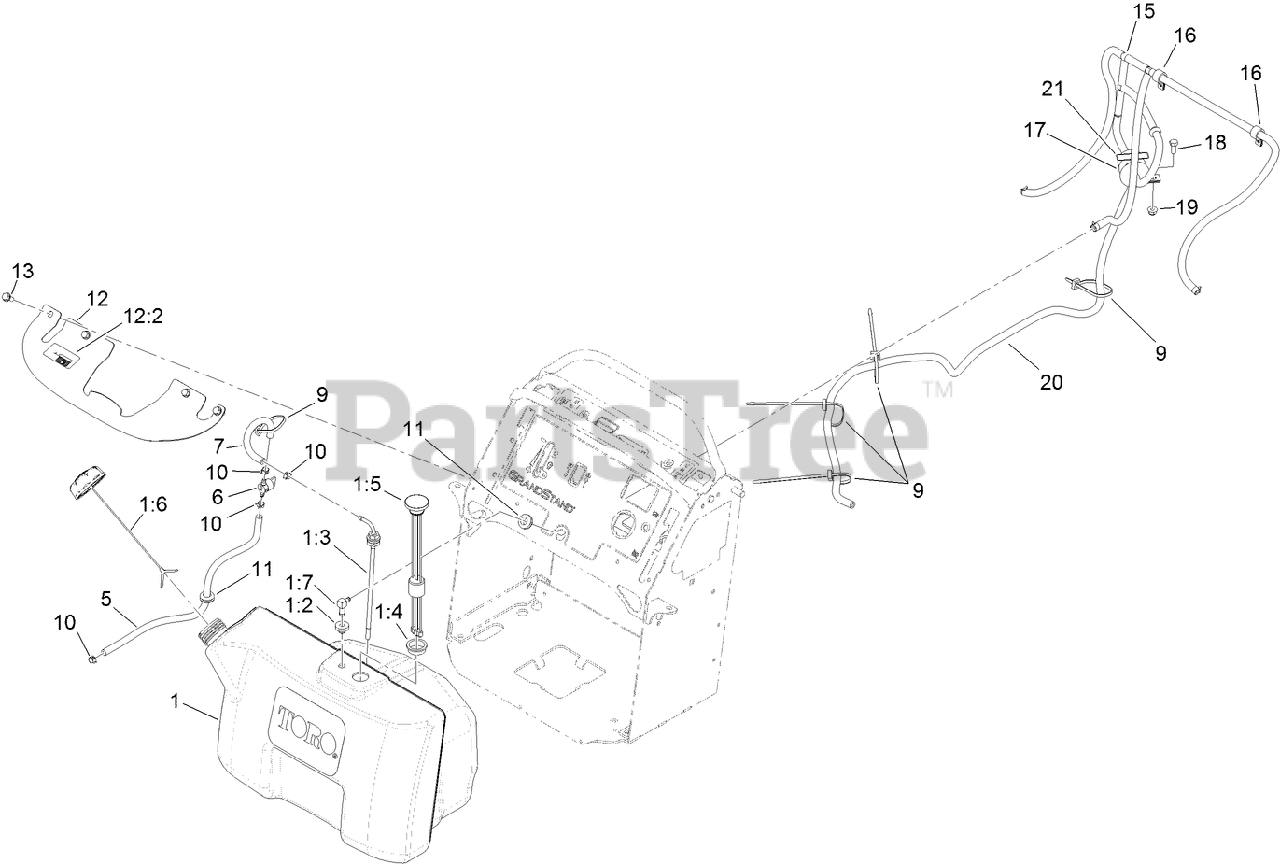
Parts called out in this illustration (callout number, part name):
1	TANK ASM
1:2	BUSHING
1:3	ELBOW-90 DEG
1:4	GROMMET
1:5	GUAGE-FUEL
1:6	CAP-FUEL, RATCHETING
1:7	FITTING-FUEL, BULKHEAD
5	HOSE-FUEL
6	VALVE-FUEL
7	HOSE-FUEL
9	TIE-CABLE
10	CLAMP-HOSE
11	GROMMET
12	BRACKET-TANK
12:2	DECAL-FILL, FUEL
13	SCREW-HWHTF
15	VENT HOSE ASM
16	CLAMP-CABLE
17	CLAMP-R
18	SCREW-HH
19	NUT-HF, NI
20	HOSE-FUEL
21	DECAL-FILTER, EMISSIONS
